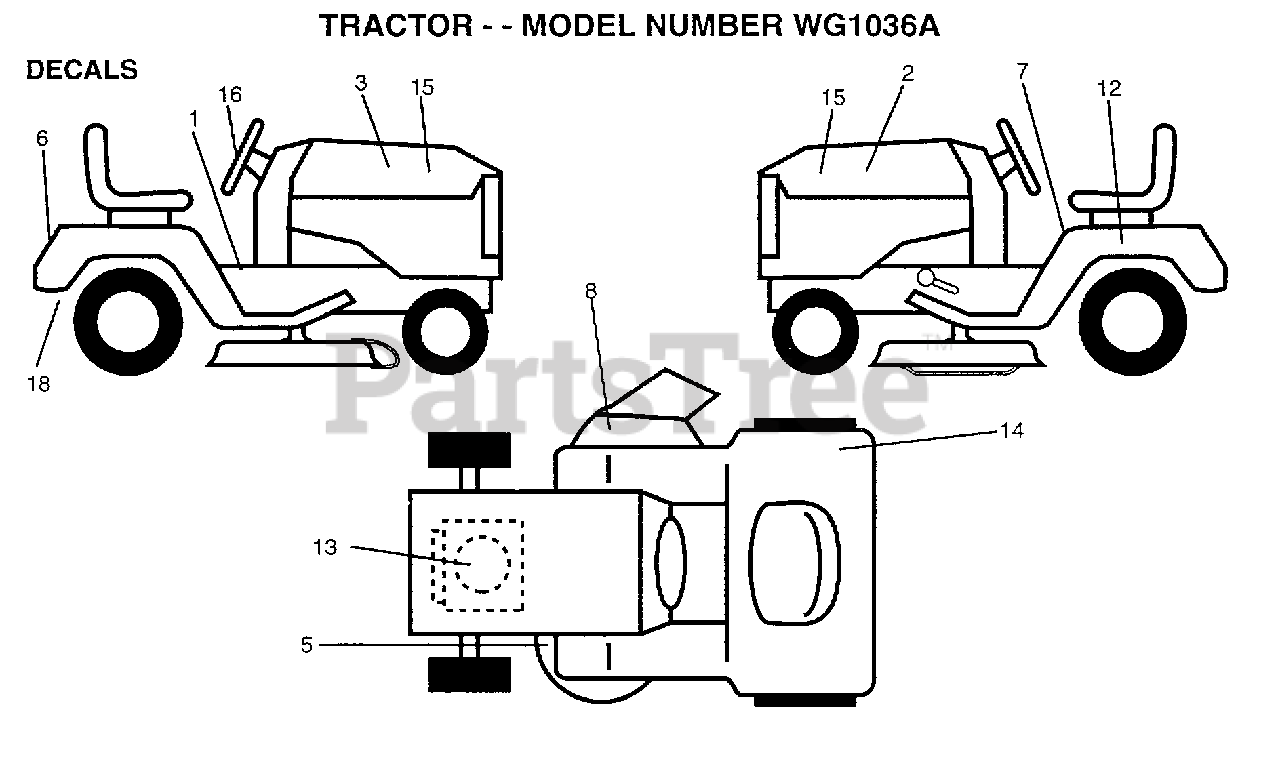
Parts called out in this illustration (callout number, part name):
1	DECAL.OP.INST.SYM
2	DECAL STRIP HD LH
3	DECAL STRIP HD RH
5	DECAL.V.BELT
6	DECAL.FENDER
7	DECAL.READ.O.MANU
8	DECAL.DANGER.CUTF
12	DECAL.BTRY.SEARS.
13	DECAL, HP, ENGINE
15	DECAL.PANEL.10HP.
16	DECAL.WHL.STRG.
18	DECAL.EURO.ST.CE.
